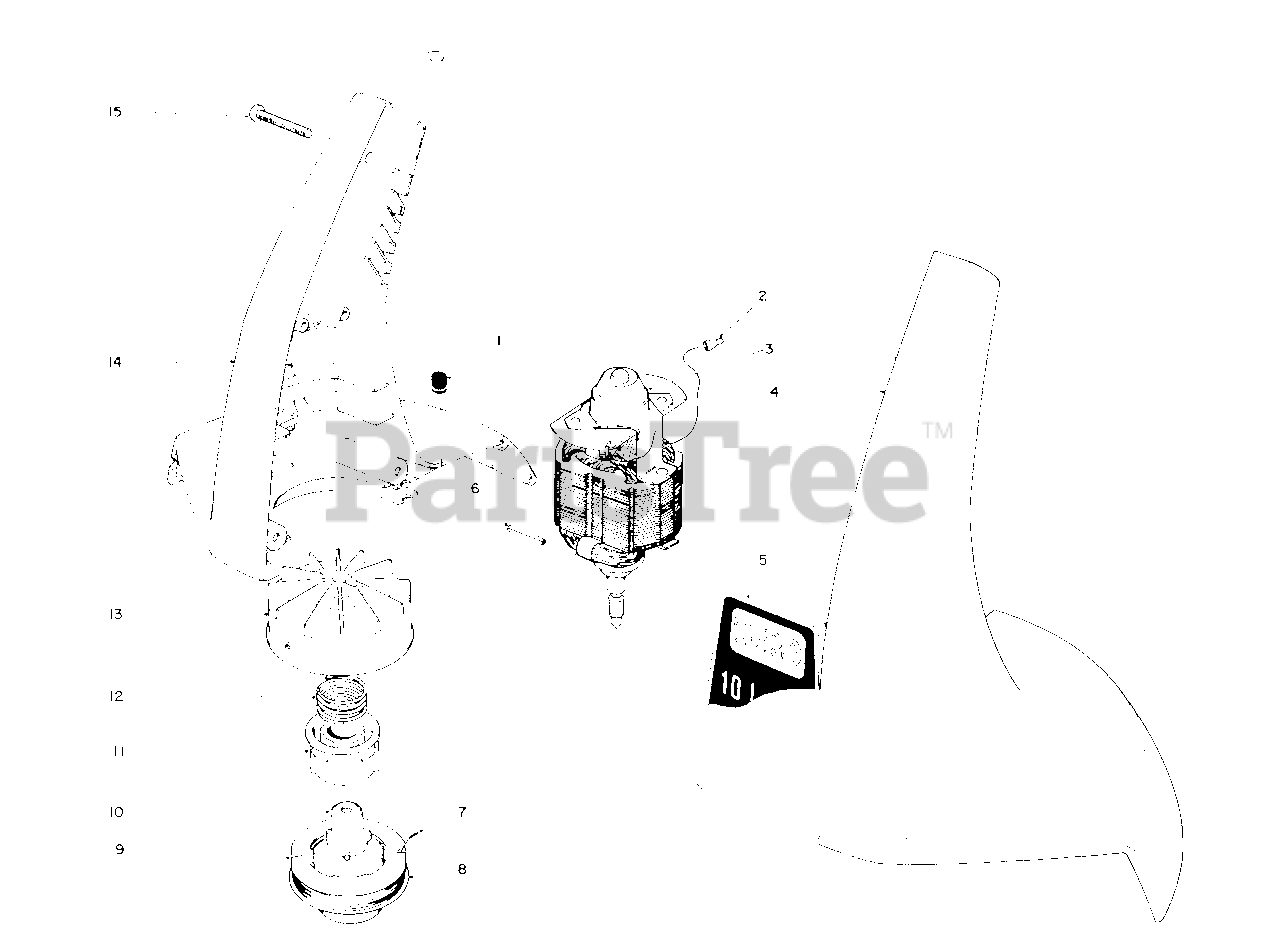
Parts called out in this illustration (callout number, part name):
2	Connector-Electric
4	Housing-L.H.
5	Decal-Housing
7	Line-Cutting (30' .05 Dia.)
8	Cap-Spool
9	Line-Cutting (30' .05 Dia.)
10	Driver-Detent
11	Core-Spool
12	Spring-Compression
13	Fan Hub Assembly
14	Housing Assembly-R.H.(Incl. Ref. #16 & 17)
15	121 Screw-Thread Forming
